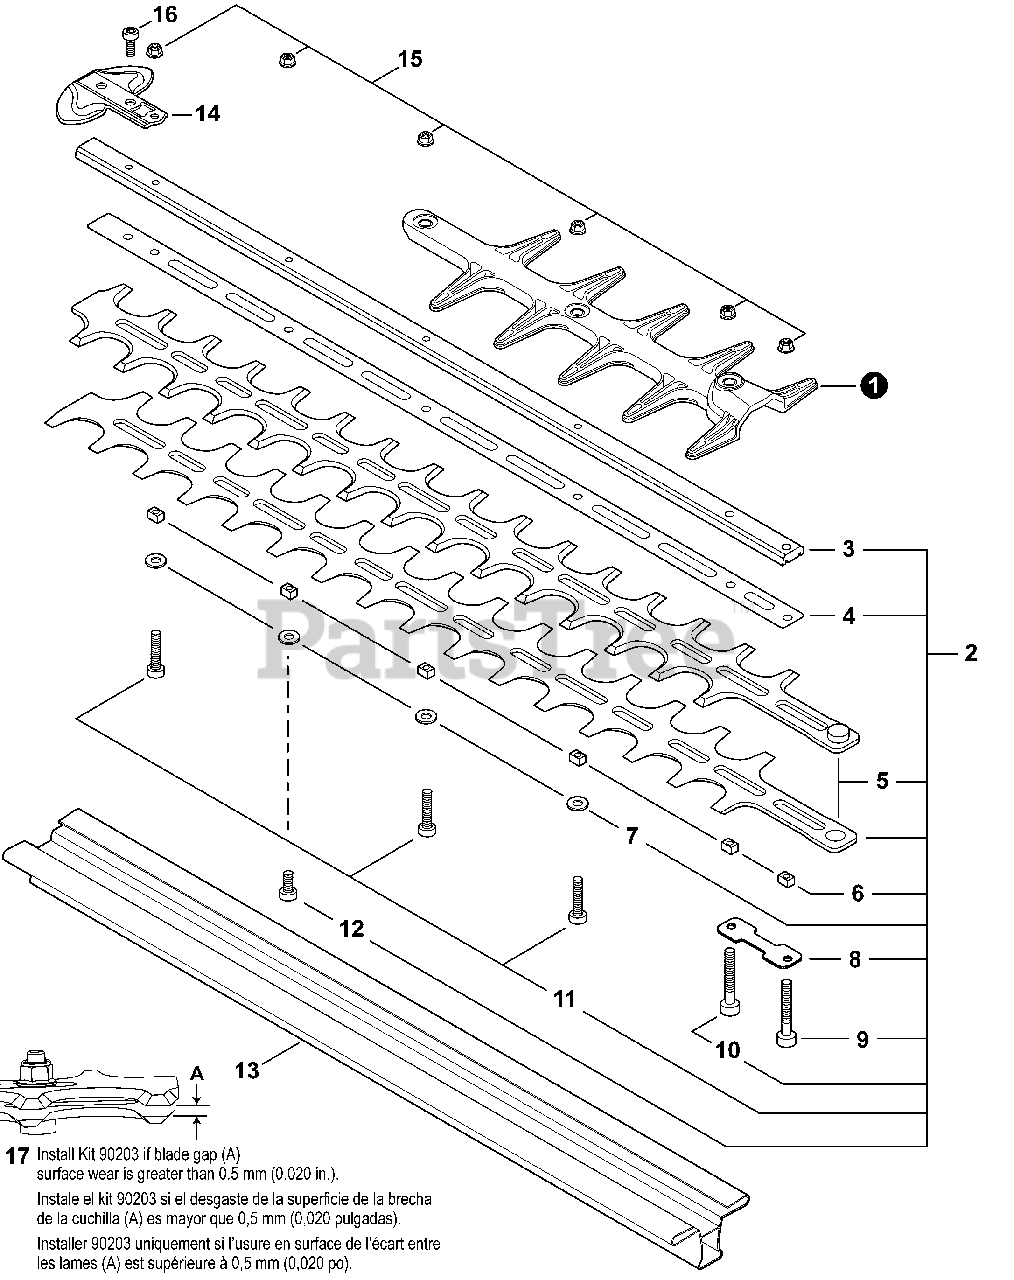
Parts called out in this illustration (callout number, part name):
1	GUARD, CUTTER BLADE
2	CUTTER ASSY, 20"
3	SUPPORT, CUTTER 20"
4	PLATE, CUTTER 20"
5	CUTTER, 20"
6	GUIDE, BLADE 5
8	PLATE, EYE
9	BOLT, TORX 5×30
10	BOLT, TORX 5×35
11	BOLT, TORX 5×25
12	BOLT, TORX 5×20
13	SCABBARD
14	GUARD, TIP
15	NUT, FLANGE M5
16	BOLT, TORX 5×8
17	BLADE KIT, ADJUSTABLE
